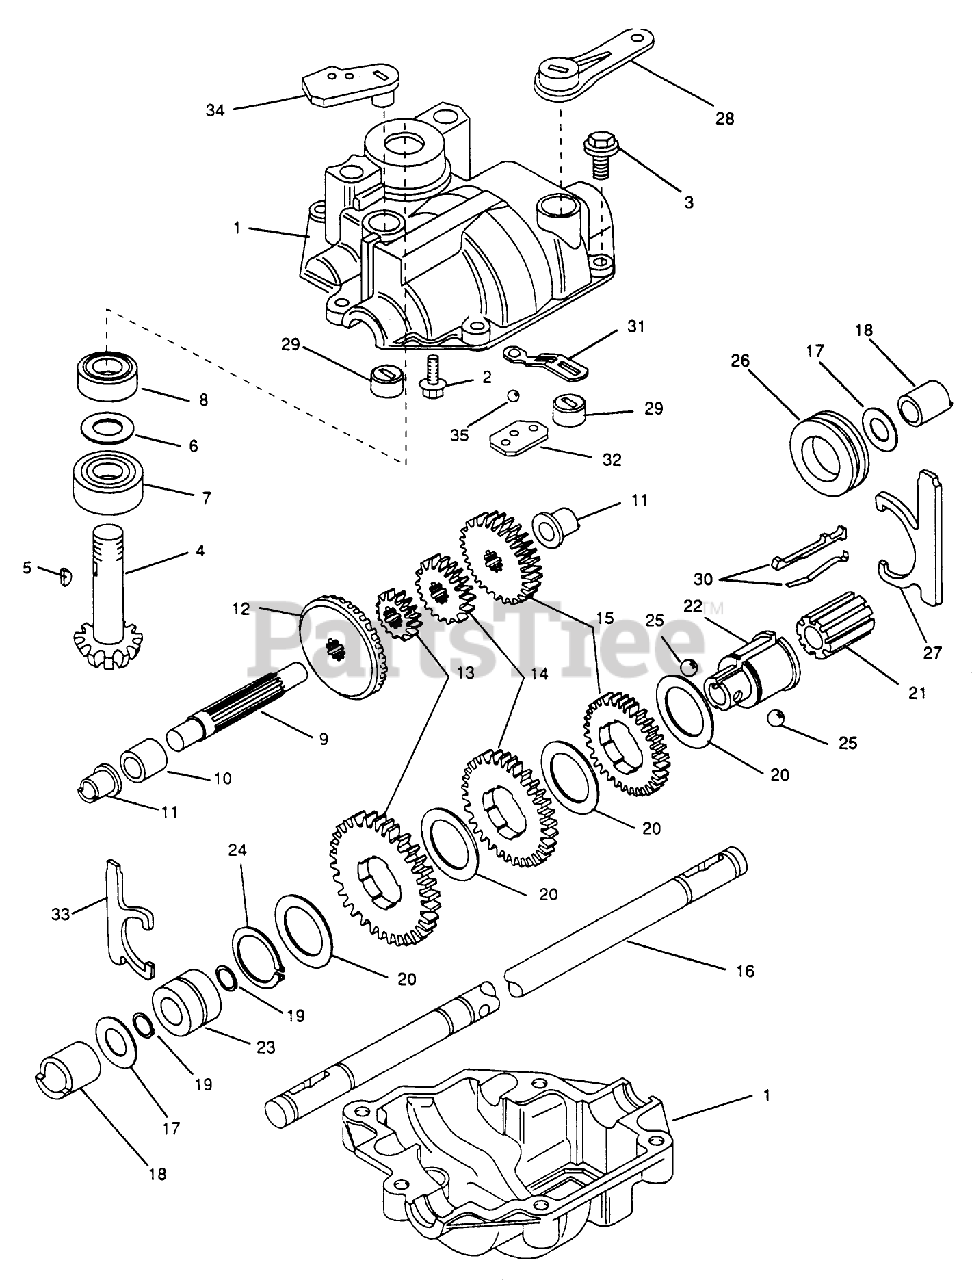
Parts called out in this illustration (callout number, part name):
5	KEY GALGER
7	BEARING
8	BEARING
12	GEAR-RING
22	COLLAR-SHFT
34	ARM - CLUTCH
